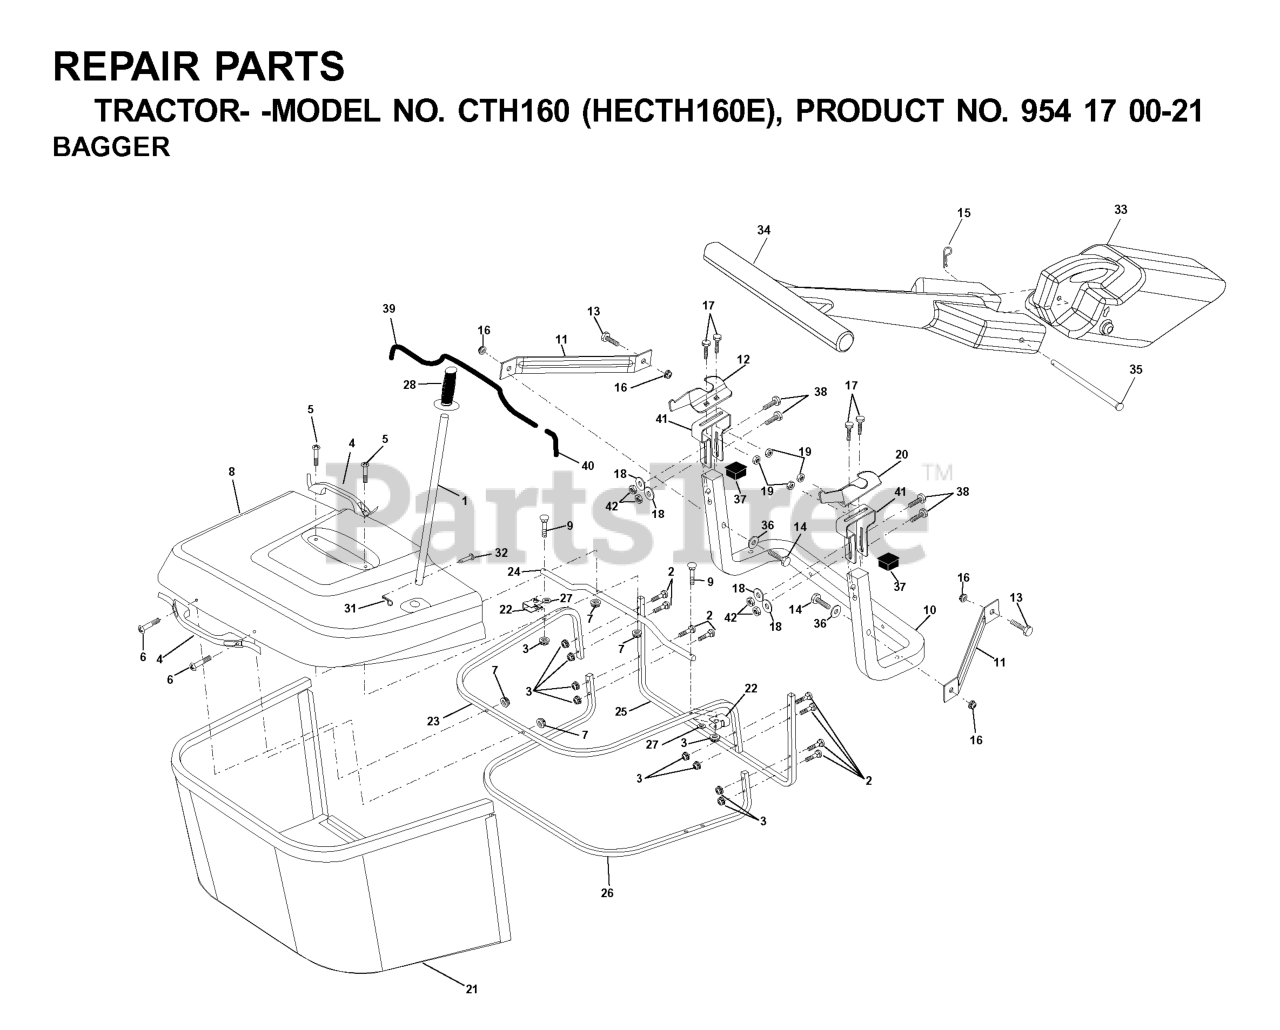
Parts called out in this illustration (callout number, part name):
1	TUBE HANDLE BAGGER
2	Bolt Carriage 1/4-20 x 2.0 Gr.5
3	NUT T
4	HANDLE.BAGGER.W/LVRS.BLK.CRD
5	SCREW.PAN.HEAD
6	REPL BY 532 75 00-29
8	COVER
9	Bolt Carriage 1/4-20 x 2.25d x Gr.5
10	TUBE
11	BRACKET.SUPPORT.UPPER.BAG.CRD
14	Bolt Hex 3/8-16 x 2-1/2 Gr. 5
15	RETAINER-SPRNG RB
16	NUT LOCK FLG 3/8-16 UNC
17	RP BOLT 5/16-18 X3/4 ZN/YEL GR
18	WASHER M
19	NUT LOCK HEX FLANGE 5/16-18
20	BRACKET
21	BAG
22	BRKT.SIDE.BAG.CRD
23	TUBE.UPPER.BAG.CRD
24	TUBE.PIVOT.BAG.CRD.BLACK
26	TUBE.LOWER.BAG.CRD
28	Grip Handle Black
31	RETAINER M
32	RIVET,DRILLED
33	MULCH PLUG, CTH150
34	HANDLE.MULCHER.92.CRD (2 2)
36	WASHER
37	Plug Support Bagger CRD
38	BOLT.5/16-18X2.5
39	TRIM
40	TRIM
41	BRKT.VERT.ADJ.BAGGER.CRD
42	NUT.71038.31-18.HEX.NYLOCK
